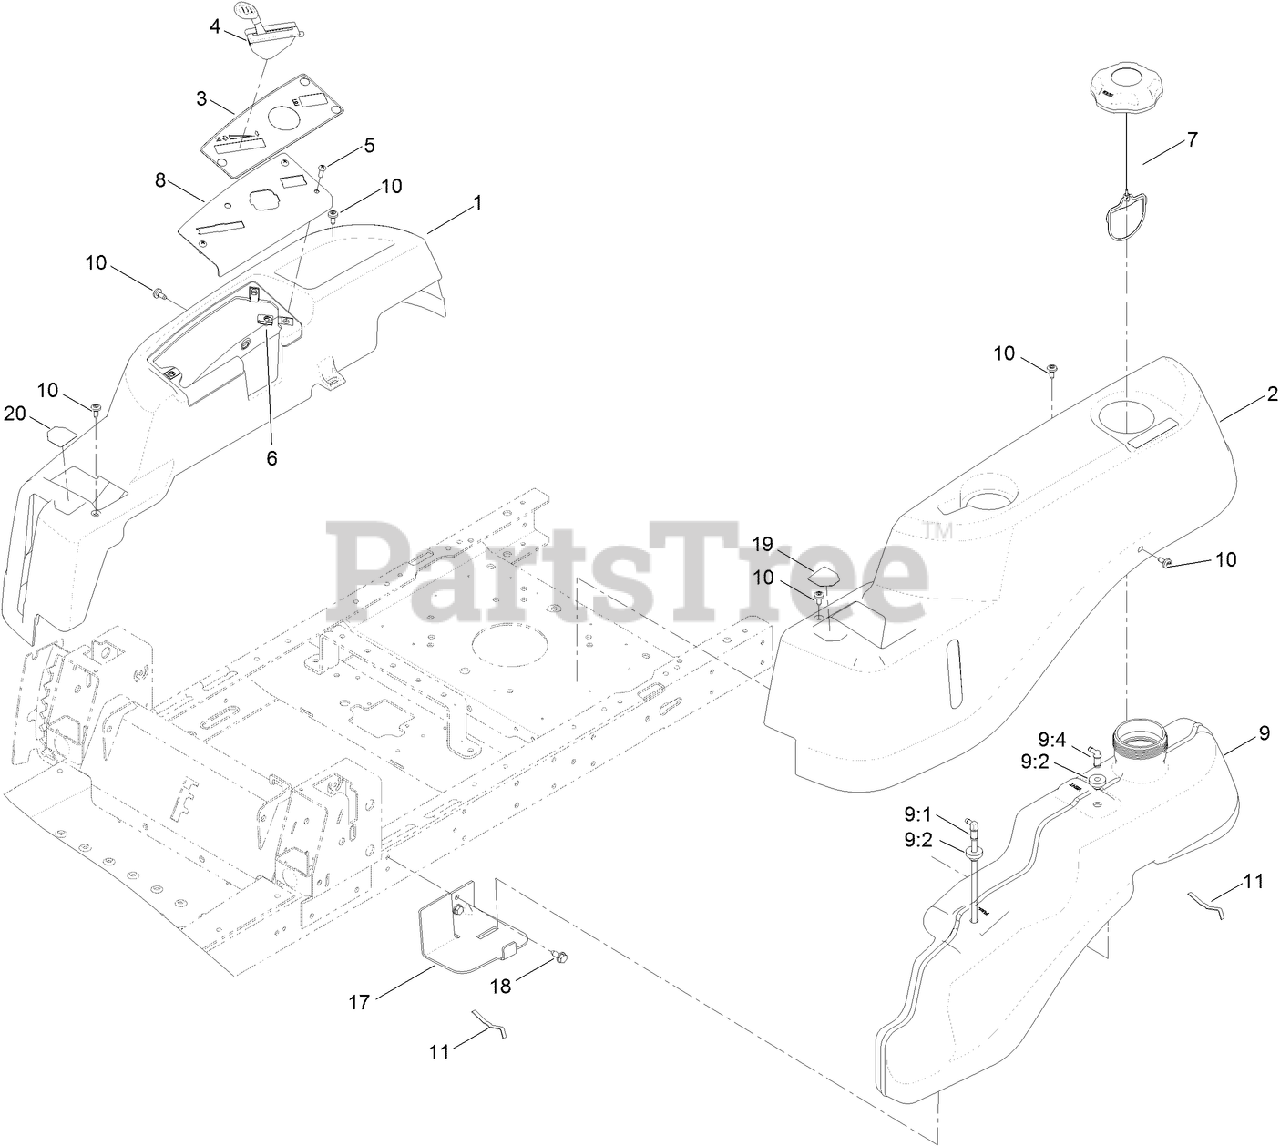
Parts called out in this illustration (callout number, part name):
1	POD-RH
3	DECAL-PANEL, CONTROL
4	CABLE-THROTTLE AND CHOKE
5	SCREW-PRH
8	PLATE-CONTROL
9	FUEL TANK ASM
9:1	CONNECTOR-ELBOW, 90 DEG
9:2	BUSHING
9:4	FITTING-PLASTIC
10	SCREW-SHOULDER
11	SPRING
17	SUPPORT-TANK, FRONT
18	SCREW-HWHTF
19	DECAL-LEVER, CONTROL (LH)
20	DECAL-LEVER, CONTROL (LH)
